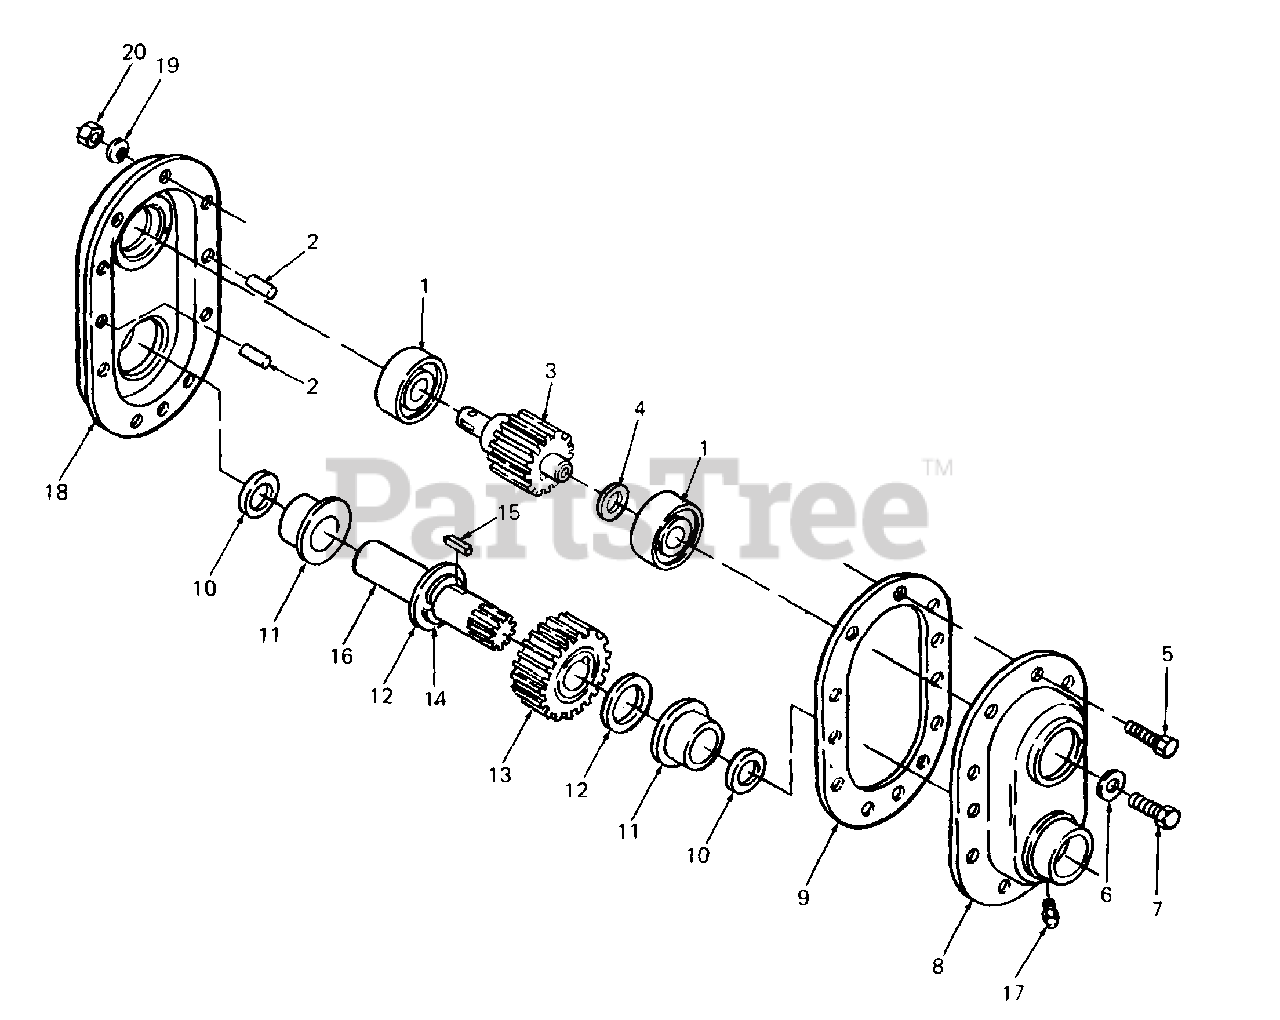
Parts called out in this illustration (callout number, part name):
1	Bearing, Ball
2	Pin, Dowel, 1/4 X 1/2
3	Shaft w/12T Gear, Input
4	Washer, Flat, 1.0 X 1.625 X .090 Thk
5	Screw, Hex Cap, 1/4-28 X 1.0 Lg GR5
6	Washer, Flat, .406 X 1.25 X .157 Thk HDN
7	Screw, Hex Patch, 3/8-24 X 1.0 Lg GR5
8	Housing Half - RH
10	Seal, Oil, 1.25 ID X 1.75 OD
11	Bearing, Flange, 1.252 ID
12	Washer, Flat, 1.25 X 2.0 X .060 Thk
13	Spur - Gear, 31T
14	Ring, Snap
15	Key, Hi-Pro, 1/4 X 7/8
16	Shaft, Splined Output
17	Fitting, Gear
18	Housing Half - LH
19	Washer, Spring, .270 X .51 X .030 Thk
20	Nut, Hex, 1/4-28
